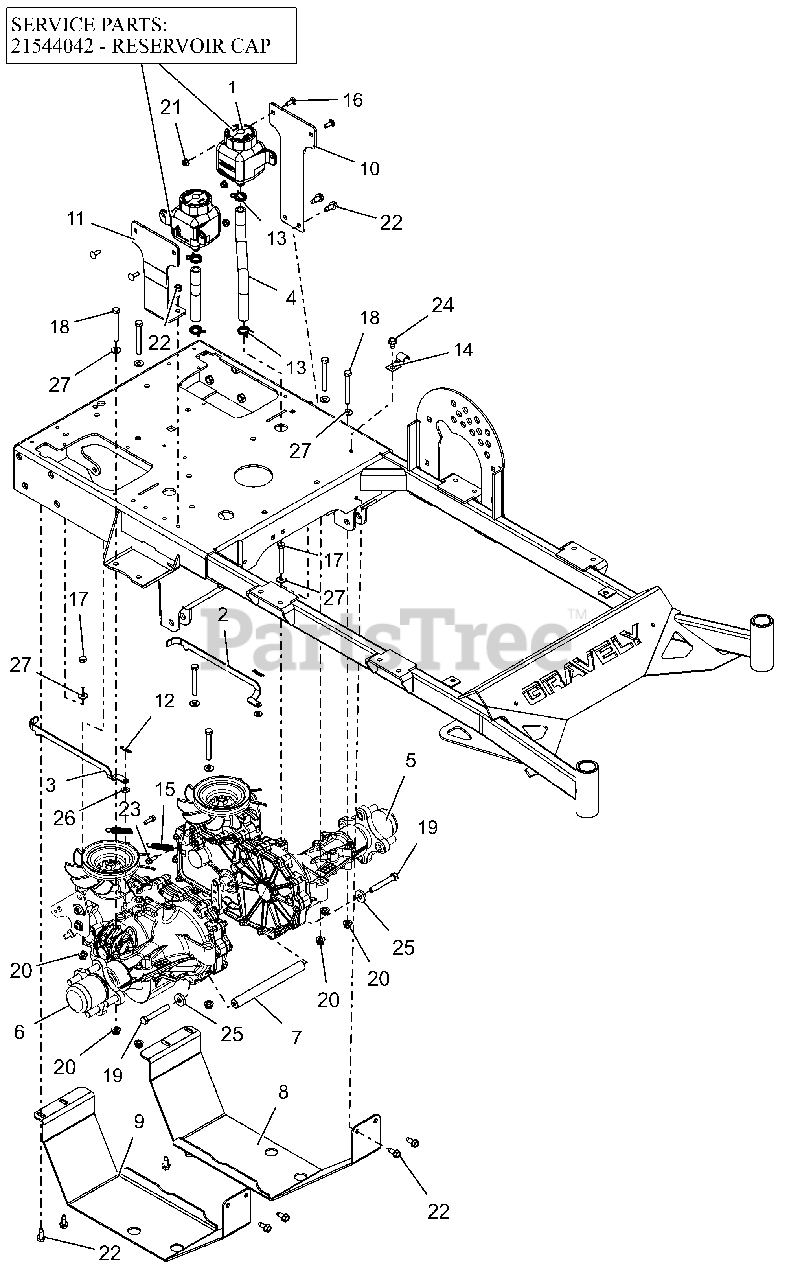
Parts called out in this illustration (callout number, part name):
1	TANK, EXPANSION
1	CAP, HYDRO RESERVOIR REPLAC.
2	BRKT, LH DUMP VALVE (BLACK)
3	BRKT, RH DUMP VALVE (BLACK)
4	HOSE, PRO WALK OVERFLOW
5	TRANSAXLE, ZT2800 - LH
6	TRANSAXLE, ZT2800 - RH
7	SHAFT, CROSS
8	PLATE, LH 36" SKID (BLACK)
9	PLATE, RH 36" SKID (BLACK)
10	BRKT, EXPANSION TANK MTG (RED)
11	BRKT, EXPANSION TANK MTG
12	PIN-HAIR, ENDRIES #25 YWZC
13	3/4 WIRE HOSE CLMP ZC
15	SPRING, EXTENSION
16	@BLT-RDHDSQNK .25-20X.75 G5YZ
17	@BLT-HEX .31-18X2.50 GR5 YWZC
18	@BLT-HEX .31-18X2.75 GR5 YWZC
19	@BLT-HEX .38-16X2.50 GR5 YWZC
20	@NUT-LK-NYL-FLG .31-18 YWZC
21	@NUT-LK-NYL-FLG .25-20 YWZC
22	@SCR-TAP .31-18X.75 HWH TR YWZ
23	SCR-TAP-PM .25-20X.75 TR YWZ
24	@SCR-TAP .31-18X.50 HWH TR YWZ
25	WSHR-FL-STL .406X1.00X.188 YWZ
26	@WSHR-FL-STL.281X.62X.065 YWZC
27	@WSHR-FL-STL.312X.734X.065 YWZ
